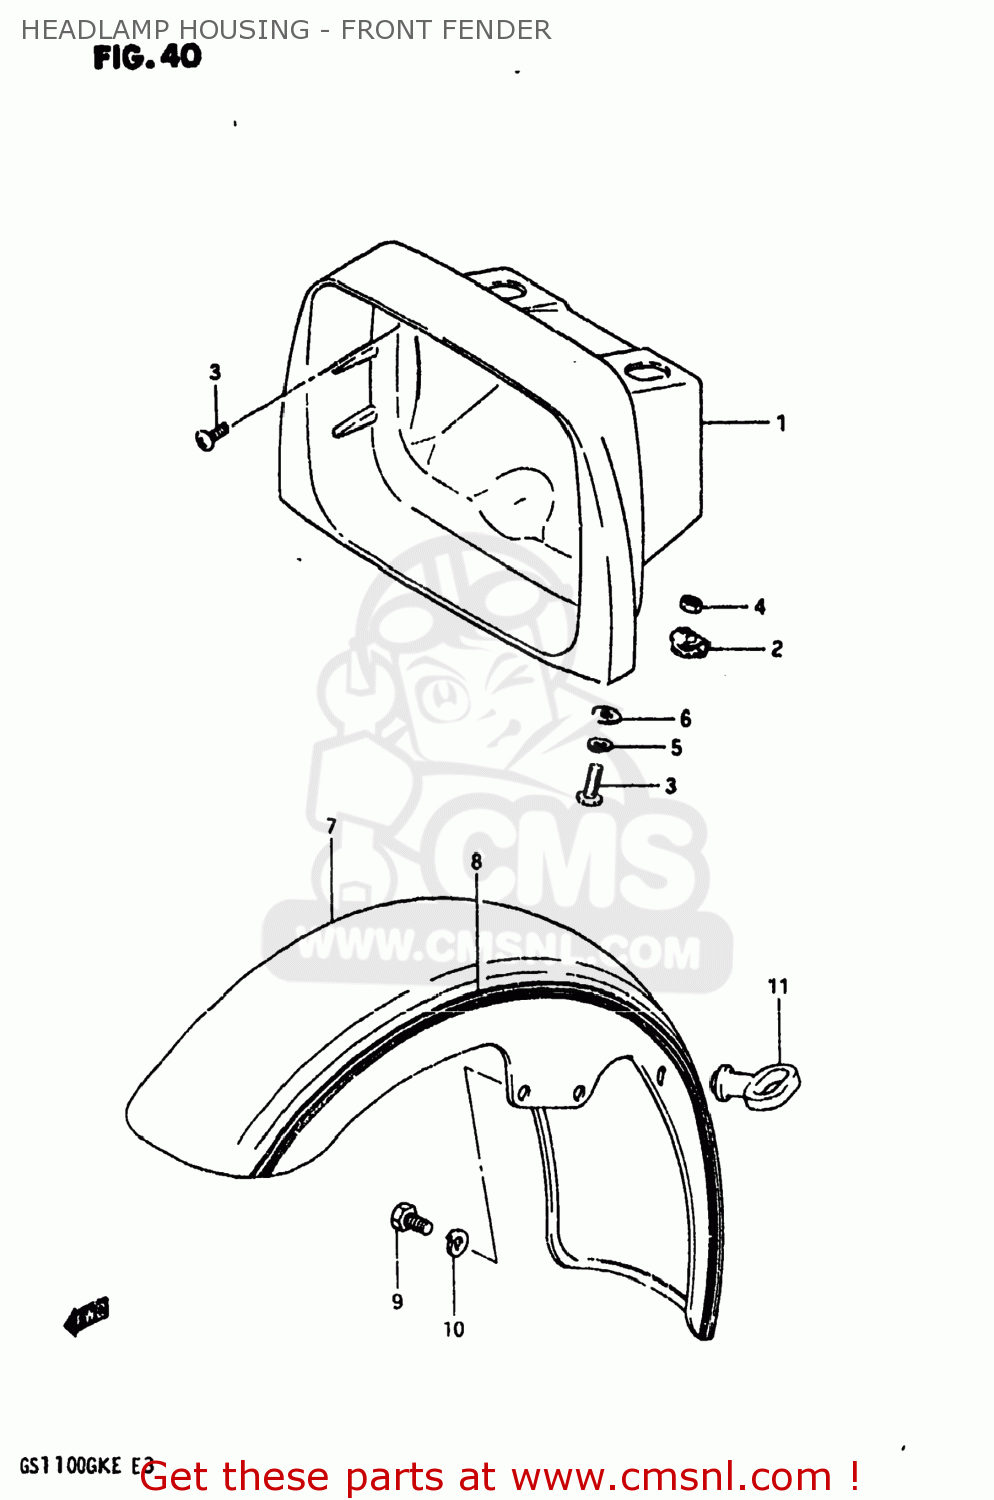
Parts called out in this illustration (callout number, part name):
1	HOUSING,HEADLAMP
2	PLATE
3	(5X20) CROSS SCREW
4	NUT
5	LOCK WASHER
6	WASHER
7	FENDER,FRONT
8	TAPE,FRONT FENDER
9	BOLT
10	LOCK WASHER
11	GUIDE,CABLE
